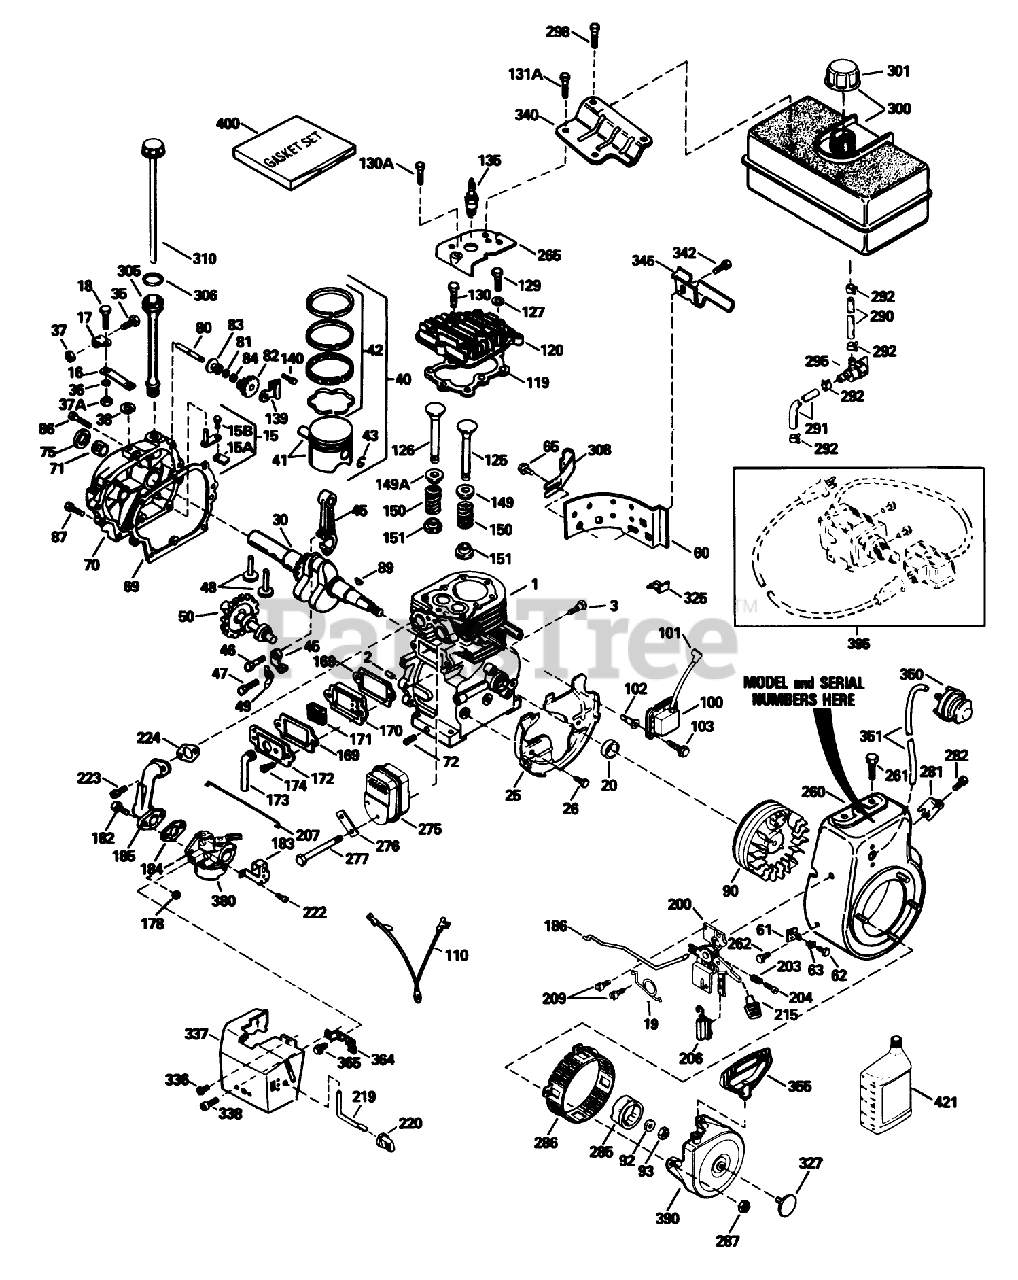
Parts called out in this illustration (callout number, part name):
1	Cylinder Asm (Includes 2, 20, 72)
2	Pin-Dowel
3	Screw (1/4-20x1/2)
15	Rod, Governor (Incl. Nos.62 63)
15A	Yoke-Governor
15B	Screw (6-40x5/16)
16	Lever-Governor
17	Clamp-Lever, Governor
18	Screw
19	Spring-Throttle
20	Seal-Oil
25	Baffle-Blower Housing
26	Screw (1/4-20x19/32)
30	Crankshaft
35	Screw
36	Washer-Lock
37	Nut-Lock
37A	Nut-Lock
38	Ring-Retaining
40	Piston, Pin Ring Assy.(Std.) (Incl. Ref. #24A, 25 26)
40	Piston, Pin Ring Assy. (.010 oversize) (Incl. Ref. #24A, 25 26)
40	Piston, Pin Ring Assy. (.020 oversize) (Incl. Ref. #24A, 25 26)
41	Piston Pin Assy. (Std.) (Incl. Ref. #26)
41	Piston Pin Assy. (.010 oversize) (Incl. Ref. #26)
41	Piston Pin Assy. (.020 oversize) (Incl. Ref. #26)
42	Ring Set (Std.)
42	Ring Set (.010" OS)
42	Ring Set (.020" OS)
45	Rod Assy., Connecting (Incl. Ref. #28 28A)
46	Bolt-Rod
47	Bolt-Rod
48	Lifter-Valve
49	Dipper-Oil
50	Camshaft (MCR)
60	Extension-Housing, Blower
61	Bracket
62	Screw (8-32 x 3/8)
63	Grommet
65	Screw
69	Cylinder Cover Gasket
70	Cover-Cylinder (Includes 71, 75, 80)
71	2025A77 WIZARD ROTA
72	Plug-Drain, Oil (SQH 1/4-18)
75	Seal-Oil
80	Shaft-Governor
81	Washer-Flat
82	Gear Assy., Governor (Incl. Ref. #45)
83	Spool-Governor
84	Ring-Retaining
86	Screw (1/4-20x1-3/16)
87	Screw (1/4-20x1-11/16)
89	Key-Flywheel
90	Flywheel (W/Ring Gear)
92	Washer-Belleville
93	Nut-Flywheel
100	Solid State ASM
101	Cover-Spark Plug
103	Screw
110	Ground Wire
119	Gasket-Cylinder Head
120	Head Cylinder
125	Valve, Exhaust (Standard)(Incl. No. 9)
125	Valve, Exhaust (1/32" oversize)(Incl. No. 9)
126	Valve, Intake (Std.) (Incl. Ref. #58)
126	Valve, Intake (1/32" oversize) (Incl. Ref. #58)
127	Washer-Flat
129	Screw (5/16-18x1-25/32)
130	Screw (5/16-18x1-1/2)
130A	Screw (1/2-20x5/8)
131A	Screw
135	Spark Plug-Resistor (R J19 L M)
139	Bracket-Gear, Governor
140	Screw (10-24x1/2)
149	Cap-Spring, Valve
149A	51106 GILSON ROTARY
150	Spring-Valve
151	Keeper-Spring, Valve
169	Gasket-Cover, Valve
170	Body-Breather
171	Element-Breather
172	Cover-Valve
173	Tube-Breather
174	Screw
178	Nut and Lock Washer (1/4-28)
182	Screw (1/4-28x1)
183	Bracket-Choke
184	Gasket-Carburetor To Intake Pipe
185	Pipe-Intake
186	Link-Governor
200	Bracket-Control (Includes 19, 203, 204, 206)
203	Spring-Compression
204	Screw
206	Terminal
207	Link-Throttle
209	Screw (10-32 x 1/2)
215	Knob-Control
219	Rod-Choke
220	Knob-Control
222	Screw (10-32 x 1/2)
223	Screw (T-30, 5/16-18x1-3/32)
224	Gasket-Pipe, Intake
260	Housing-Blower
261	Screw (5/16-18x3/4)
262	Screw
265	Cover-Cylinder Head
275	Muffler
276	62513 SNWTHWR W/284
277	Screw
281	Screw
282	Screw (8-32 x 3/8)
285	Cup-Starter
286	Screen-Starter
287	Nut and Lock Washer (1/4-28)
290	Line-Fuel (8.62)
291	Line-Fuel
292	Clamp-Line, Fuel
295	Valve-Shut Off, Fuel
298	Screw (1/4-15x7/8)
300	Tank-Fuel (Includes 292, 301)
301	Cap-Fuel
305	Tube-Fill, Oil
306	O-Ring
308	Clip-Tube, Fill
310	Dipstick
325	Clip-Wire
327	Plug Starter
336	Screw (10-32x1/2)
337	Cover-Carburetor
338	Screw (10-32 x 3/8)
340	Bracket-Tank, Fuel
342	Screw (1/4-20x19/32)
345	Bracket-Tank, Fuel (Black)
350	Primer-Asm
351	Line-Primer
355	Handle-Starter, Mitten Grip
364	Bracket-Carburetor
365	Screw (8-32x27/64)
380	Carburetor (Incl. Ref. #184)
390	Starter-Rewind
395	Electric Starter Kit. (Optional) Order as an Accessory
400	Gasket Set (Incl. items marked *)
421	Oil-Engine (SAE 5W30)
